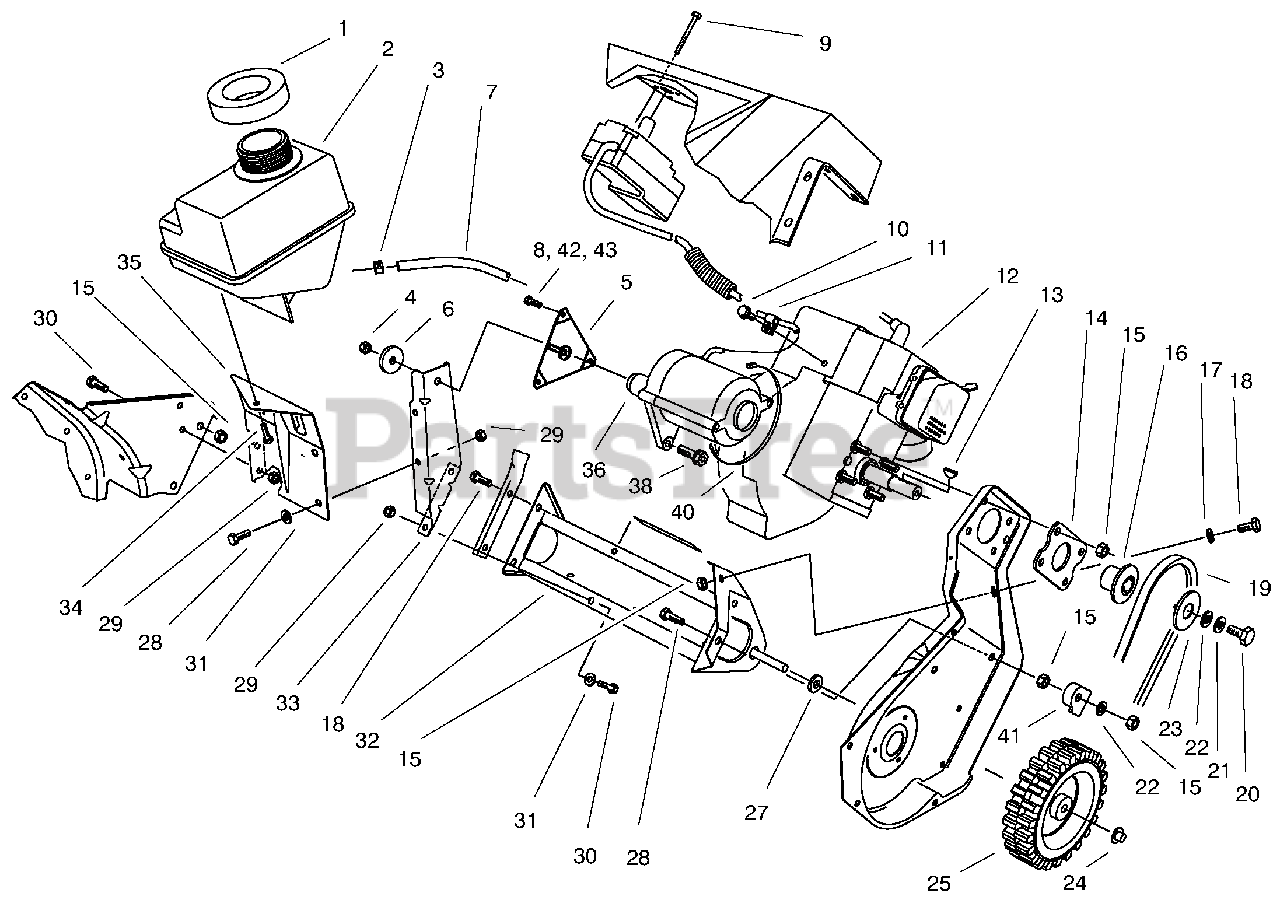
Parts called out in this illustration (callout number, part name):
1	Seal-Fuel Tank
2	Tank-Fuel
3	Clamp-Hose
4	Nut-Lock
5	Bracket & Stud Assembly
6	Washer-Engine Support
7	Hose-Fuel
8	Screw-Thread Forming
9	Screw-Thread Forming
10	Screw-Thread Forming
11	Clamp-Cable
13	Key-Woodruff
14	Plate-Engine
15	Nut-Lock
16	Hub-Sheave
17	Washer-Flat
18	Screw-Hex. Hd.
19	Belt-Drive
20	Screw-Locking Hex. Hd.
21	Washer-Belleville
22	Washer-Flat
23	Cap-Sheave
27	Spacer-Wheel
28	Screw-Hex. Hd.
29	Nut-Lock
30	Screw-Hex. Hd.
31	Washer-Flat
32	Frame Assembly
33	Support-Engine
34	Screw-Thread Forming
35	Bracket-Fuel Tank
36	Starter Motor Assembly
38	Screw-Hex. Torx
40	Strap-Starter Tie Down
41	Guide-Cable
43	Washer-Lock
